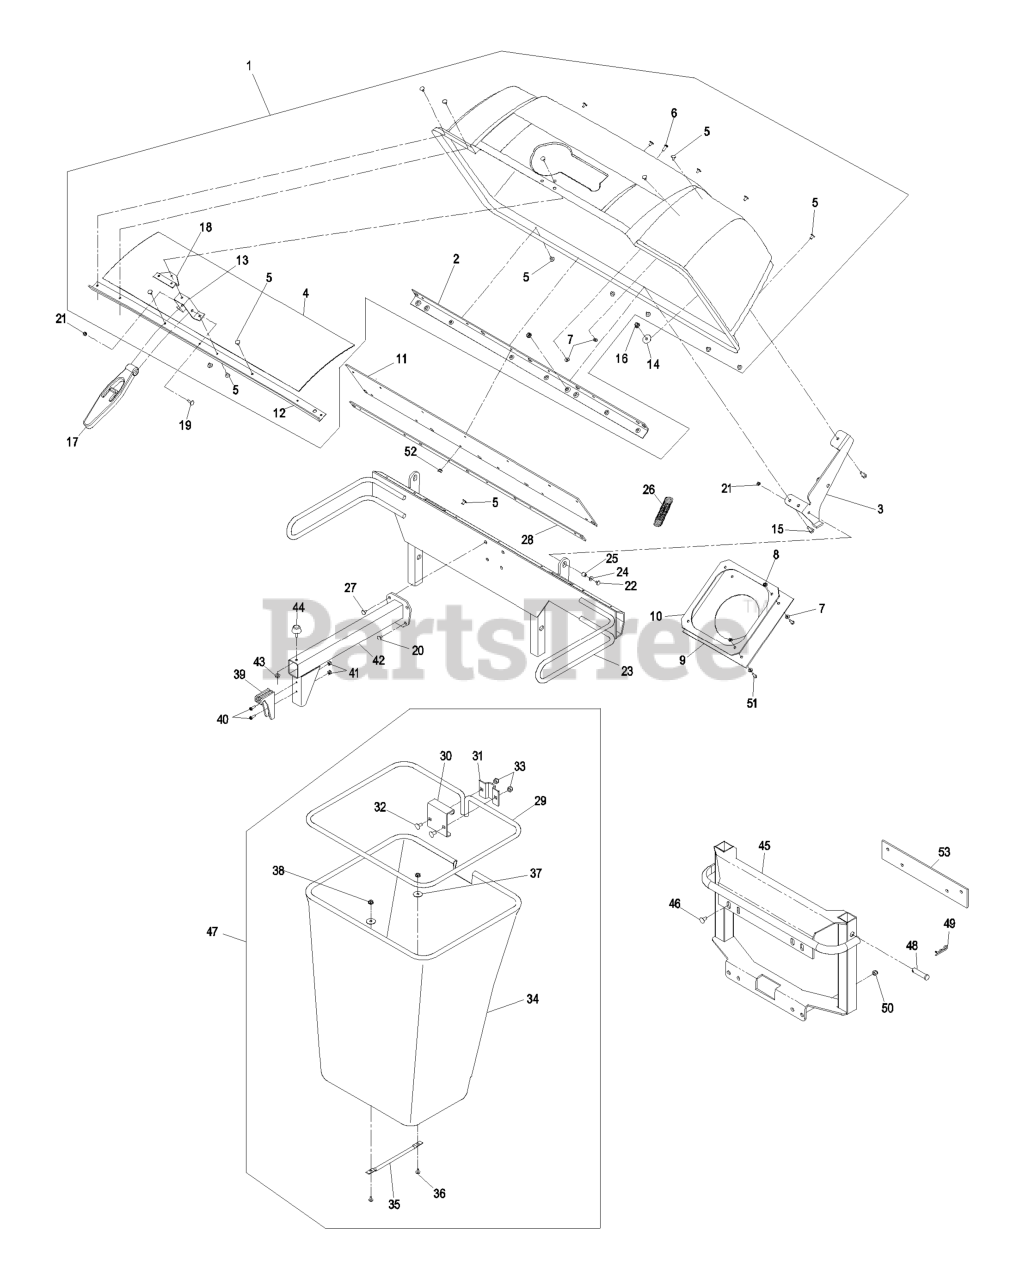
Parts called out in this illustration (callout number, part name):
1	ASM, HOOD
2	STIFFENER-BAGGER, TOP
3	HINGE ASM
4	SCREEN-BAGGER
5	RIVET-BLIND
6	SCREW-HEAD, TRUSS
7	WASHER-FLAT
8	NUT-LOCK, NI
9	SEAL-CHUTE
10	CLAMP-SEAL
12	SUPPORT-SCREEN
13	ANCHOR-LATCH
15	SCREW-HH
18	REINFORCEMENT-LATCH
19	SCREW-HH
20	SCREW-HH
21	NUT-LOCK, NI
22	SCREW-HH
23	BAGGER UPRIGHT ASM
24	WASHER-FLAT
26	SPRING-EXTENSION
27	SCREW-HSBH
28	PLATE-BACKING
29	FRAME-BAG
30	HANGER-BAG
32	BOLT-CARR
33	NUT-LOCK, NI
35	HANDLE-BAG
36	BOLT-CARR
38	NUT-LOCK, NI
40	SCREW-PPH
42	SUPPORT-BAG
45	BAGGER MOUNT ASM
46	SCREW-HH
48	PIN-CLEVIS
49	PIN-COTTER
50	NUT-HF
51	SCREW-PPH
52	NUT-LOCK, SIDE
53	SPACER,COUNTERWEIGH
